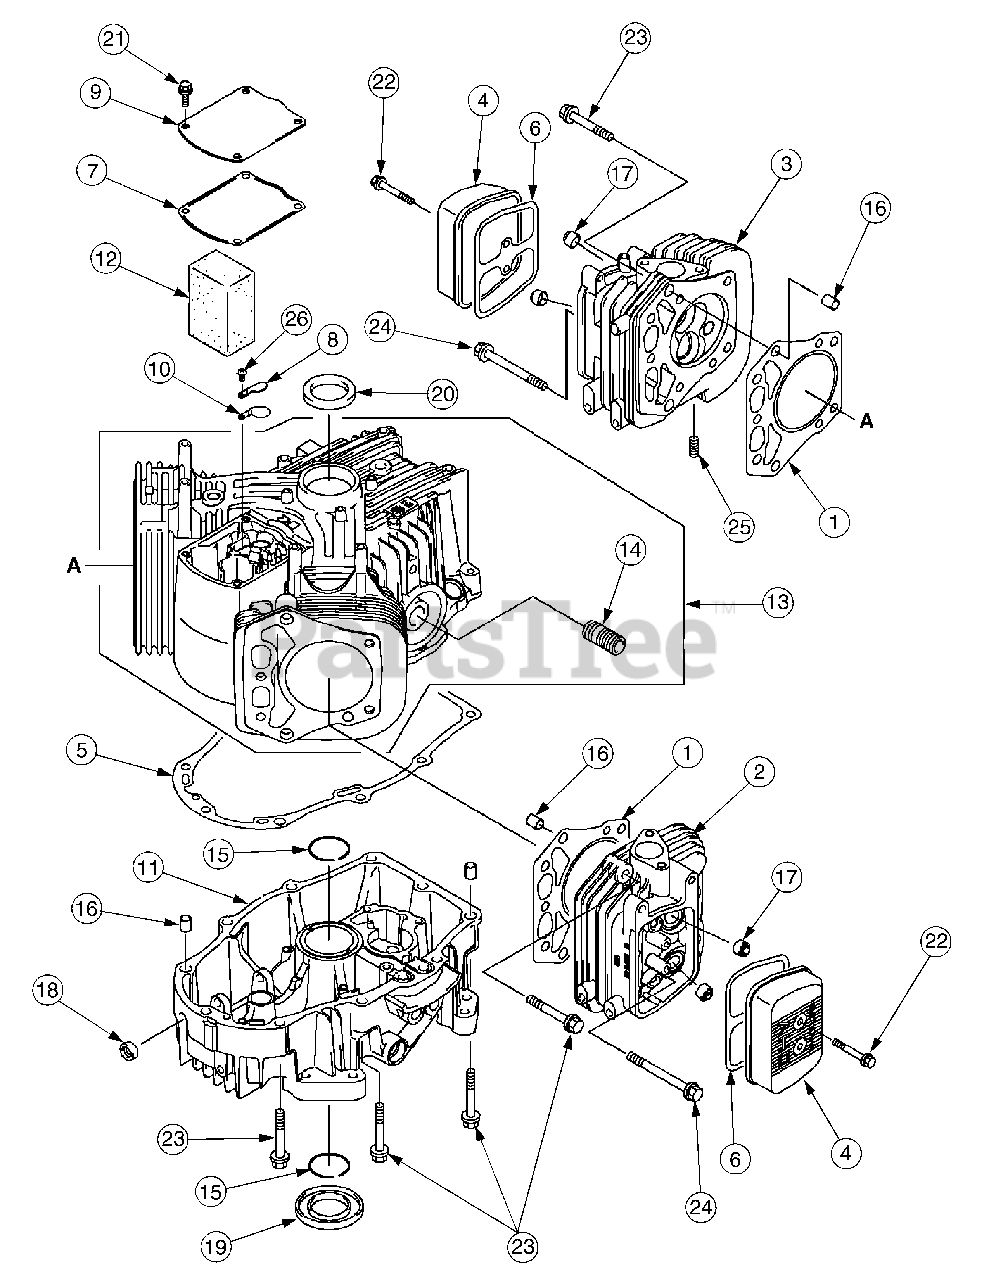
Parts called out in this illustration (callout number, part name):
2	Head, Complete- Cylinder #2
3	Head, Complete- Cylinder #1
4	Case, Rocker
5	Gasket, Crankcase Cover
6	Gasket, Rocker Case
7	Gasket, Breather
11	Cover, Crankcase
12	Element, Breather
13	Crankcase - Complete
17	Seal, Oil, RVC2, 6 x 11 x 10.2
18	Seal, Oil, SO 8 x 14 x 5 HS
19	Seal, OIl, SD 35 x 62 x 8 L HS
20	Seal, Oil, SD 35 x 52 x 7 R HS
21	Bolt, Flanged
22	Bolt, Flanged
23	Bolt, Flanged
24	Bolt, Flanged
25	Bolt, Stud
26	Screw, Pan
